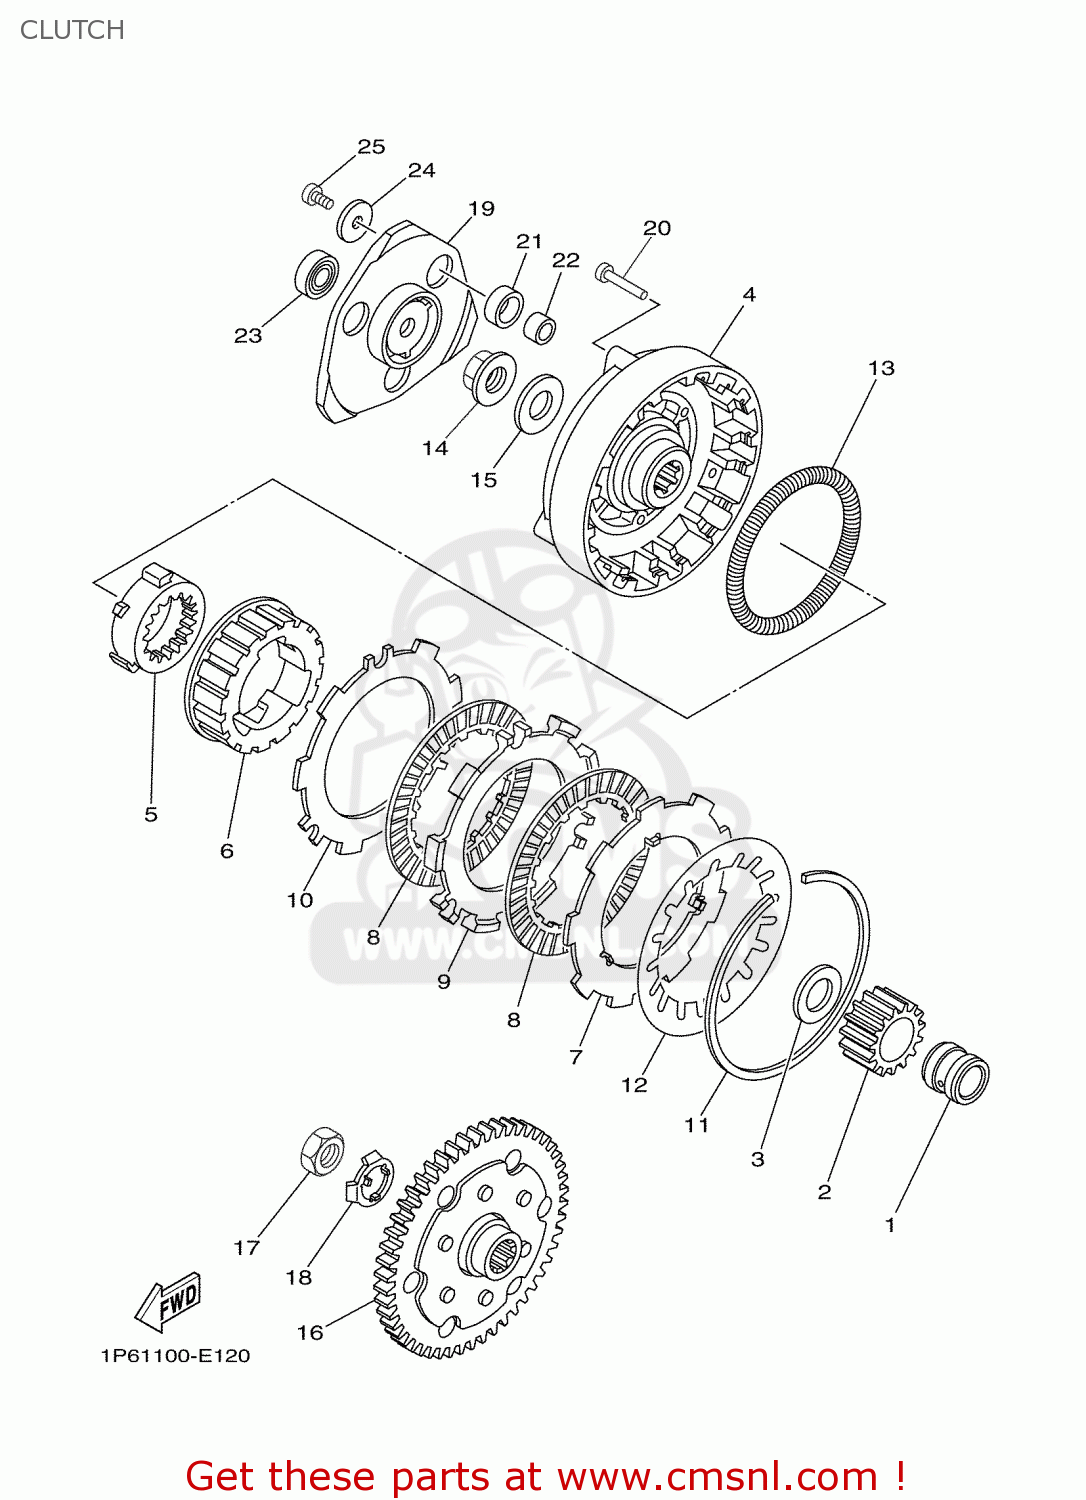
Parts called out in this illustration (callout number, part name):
01	COLLAR 1
02	GEAR, PRIMARY DRIVE
03	WASHER, PLATE
04	HOUSING, CLUTCH
05	GEAR, OUTER DRIVE
06	BOSS, CLUTCH
07	PLATE, CLUTCH 1
08	PLATE, FRICTION 2 (NAS)
09	PLATE, CLUTCH 2
10	PLATE, CLUTCH 3
11	CIRCLIP, CLUTCH
12	SPPRING, DISK
13	SPRING, GARTER
14	NUT
15	WASHER, CONICAL SPRING
16	PRIMARY DRIVEN GEAR COMP.
17	NUT, LOCK
18	WASHER, LOCK
19	PLATE, PRESSURE 1
20	PIN, GUIDE
21	BUSH
22	ABSORBER 2
23	BEARING
24	WASHER, PLATE
25	SCREW, PAN HEAD
